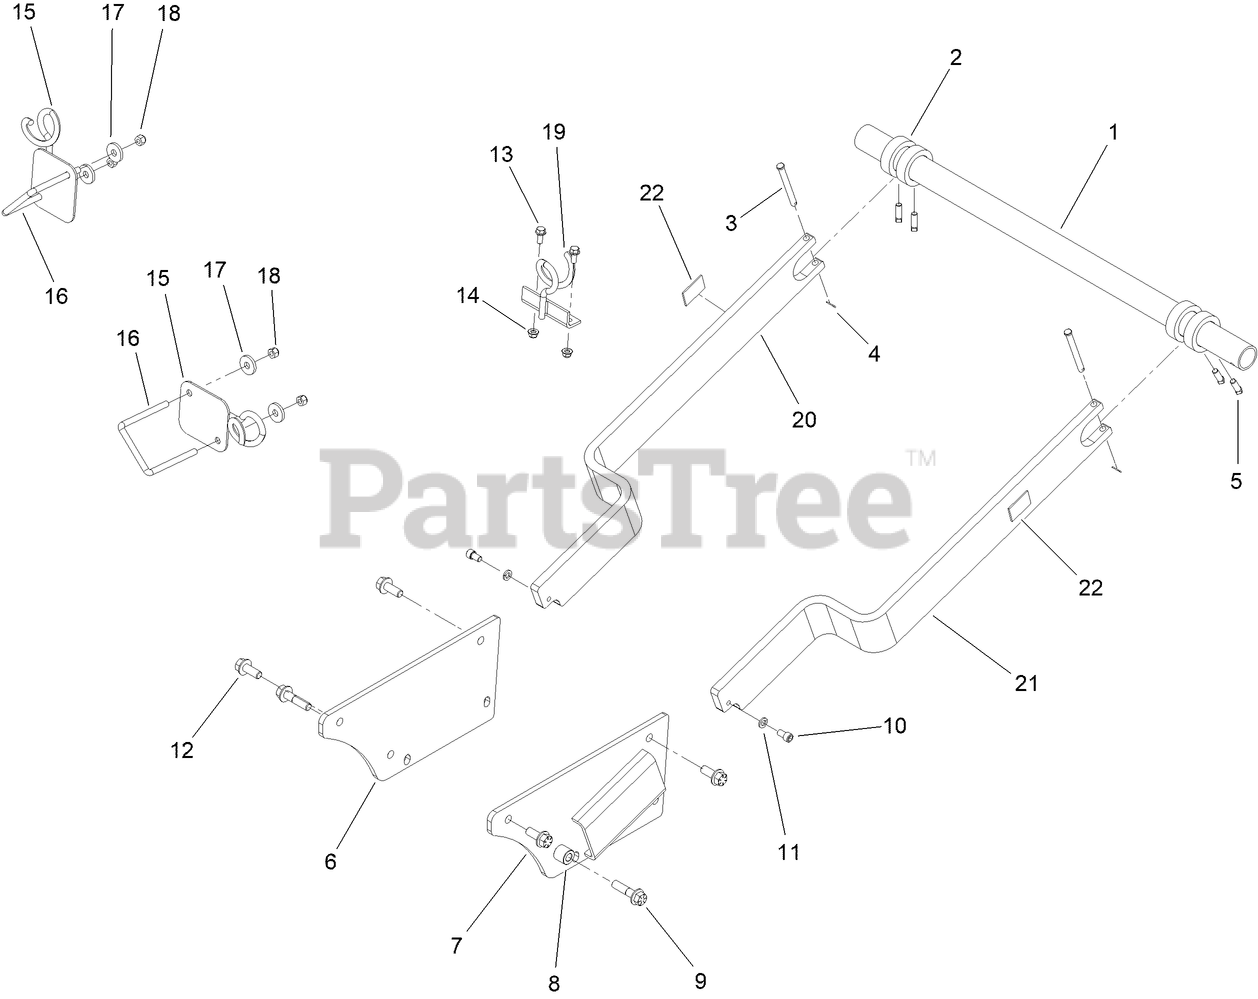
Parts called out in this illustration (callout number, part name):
2	COLLAR-STOP
3	PIN-CLEVIS
4	PIN-COTTER
5	SCREW-SET, SQH
6	TRENCHER MOUNT - LH
7	TRENCHER MOUNT - RH
8	SPACER (1.00 X .53 X .875)
9	SCREW-HF
10	BOLT (3/8-NC X 5/8", SOC, ZP)
11	WASHER-LOCK
12	SCREW-HHF
13	SCREW-HHF
14	NUT-HF, NI
15	GUIDE - CABLE (PAINTED)
16	U-BOLT (4 INCH)
17	WASHER
18	NUT-LOCK, NI
19	GUIDE - CABLE (PAINTED)
20	ARM - LH REEL CARRIER (PAINTED)
21	ARM - RH REEL CARRIER (PAINTED)
22	REEL CARRIER RATED CAPACITY
